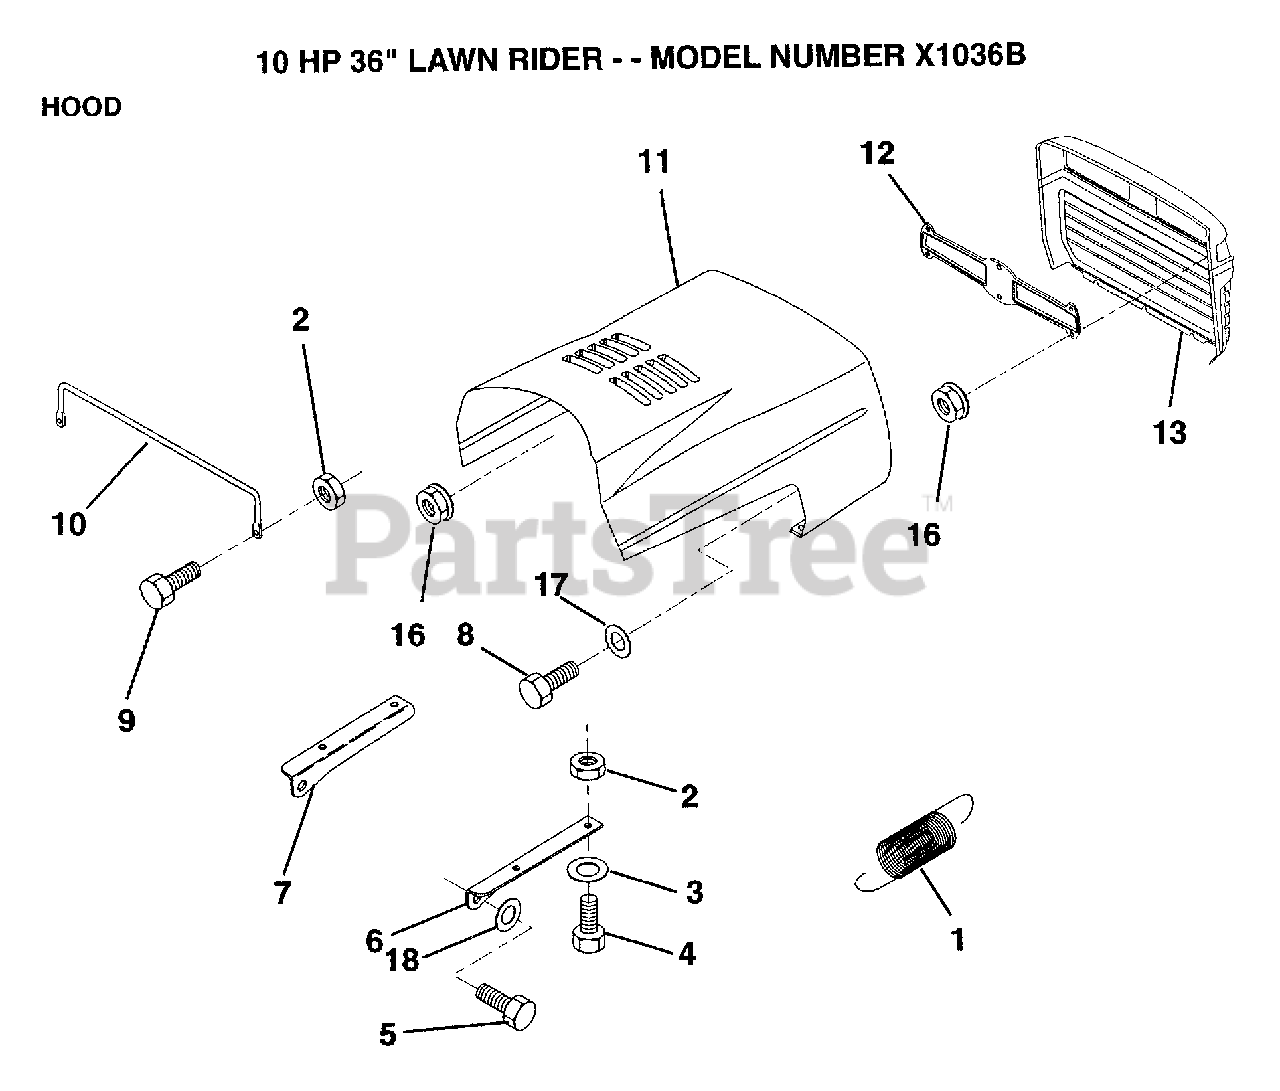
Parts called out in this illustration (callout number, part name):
2	NUT
3	WASHER
4	BOLT
6	BRKT HOOD RH
7	BRKT HOOD LH
10	"BRACE,HOOD"
13	GRILL (BLACK)
16	NUT
17	WASHER PM
18	WASHER
